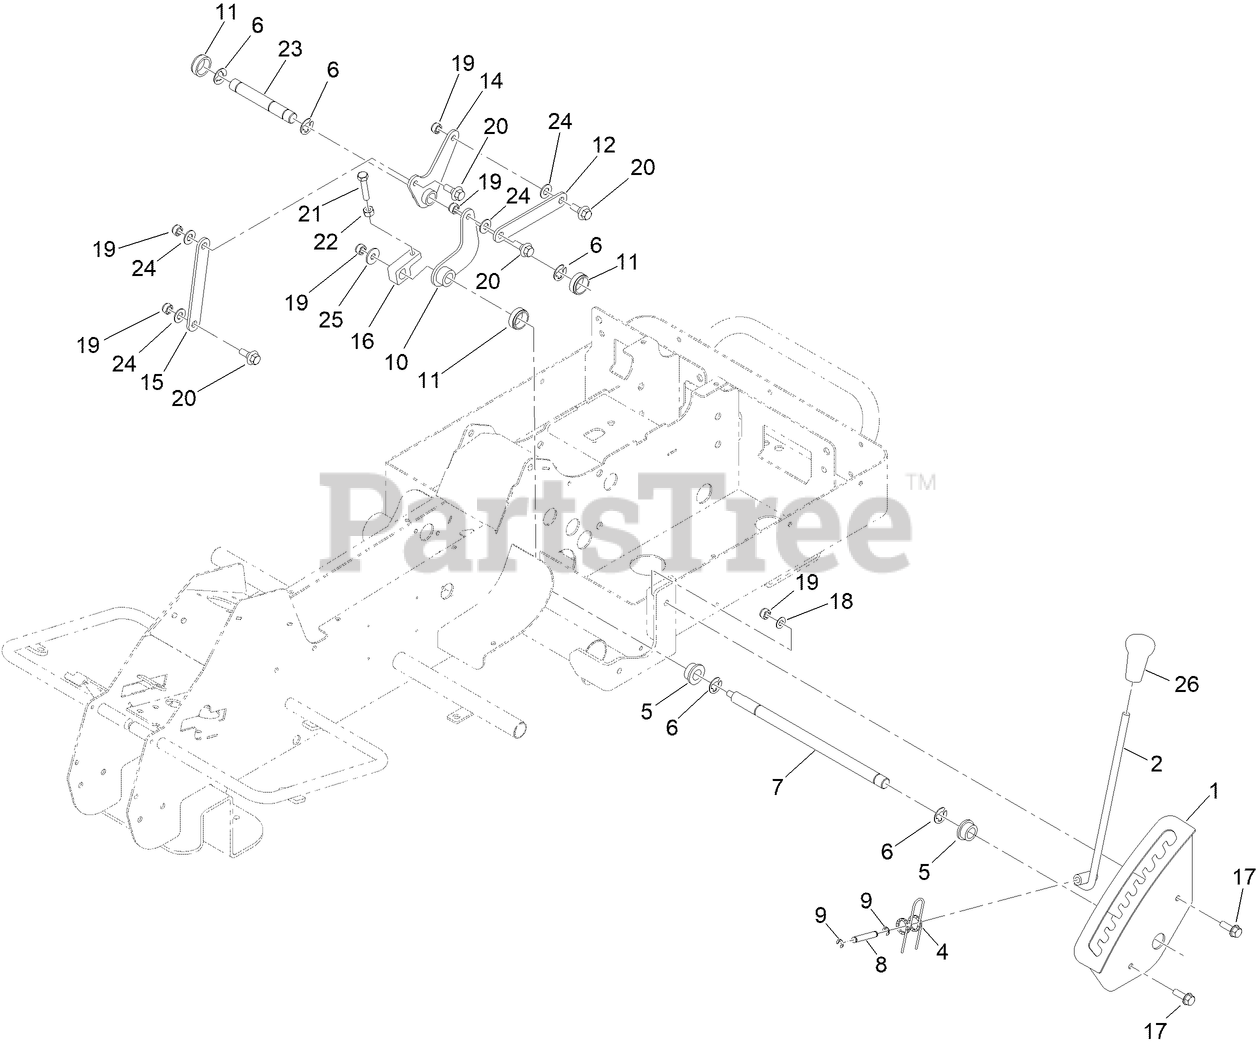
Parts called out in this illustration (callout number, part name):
1	HOC PLATE ASM
2	HOC LEVER ASM
4	SPRING, HOC LEVER
5	BUSH, HOC SHAFT
6	CLIP, HOC SHAFT
7	HOC SHAFT
8	SHAFT, HOC LEVER
9	CLIP, HOC LEVER SHAFT
10	HOC ROTATION PLATE ASM (SMALL)
11	BUSH, HOC SHAFT
12	SHORT PLATE, HOC
14	PLATE, ROTATION LARGE (HOC)
15	LONG PLATE, HOC
16	ADJUSTMENT, HOC
17	SCREW-HHF
18	WASHER-PLAIN
19	NUT-HEX, NI
20	BOLT, FLANGE
21	BOLT
22	PLAIN NUT
23	SHORT SHAFT, HOC LEVER
24	WASHER-PLAIN
25	WASHER
26	HOC, GRIP
